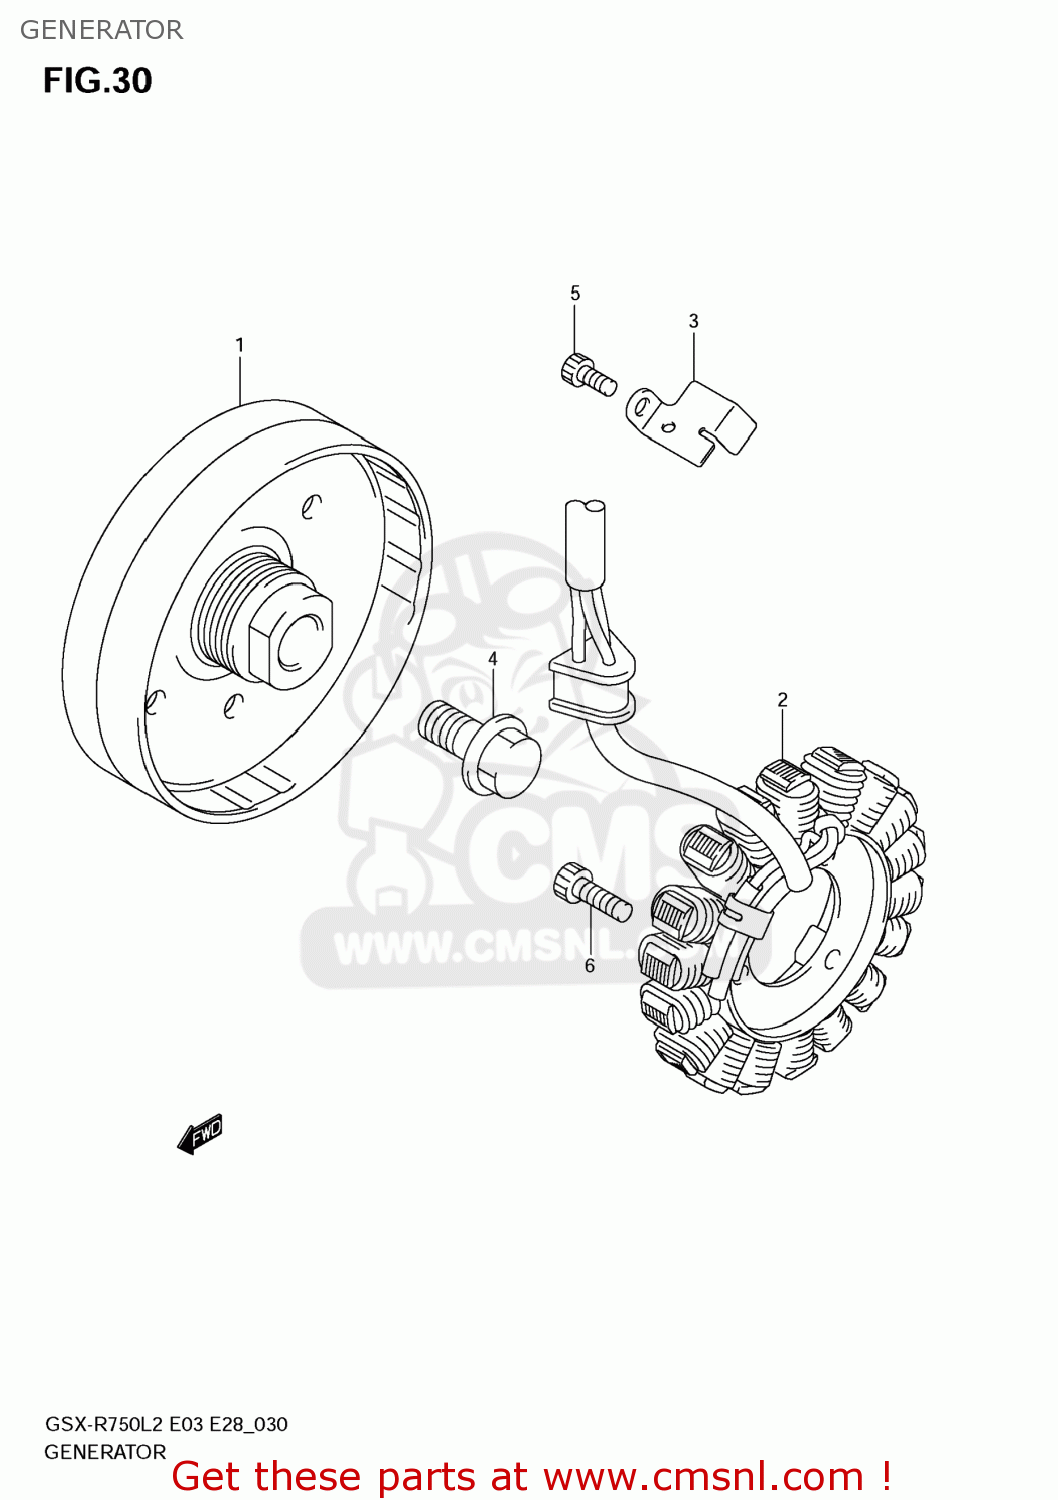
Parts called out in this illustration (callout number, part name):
1	ROTOR ASSY
2	STARTER ASSY
3	CLAMP,GENERATOR LEAD WIRE
4	BOLT,GENERATOR ROTOR
5	BOLT
6	BOLT
